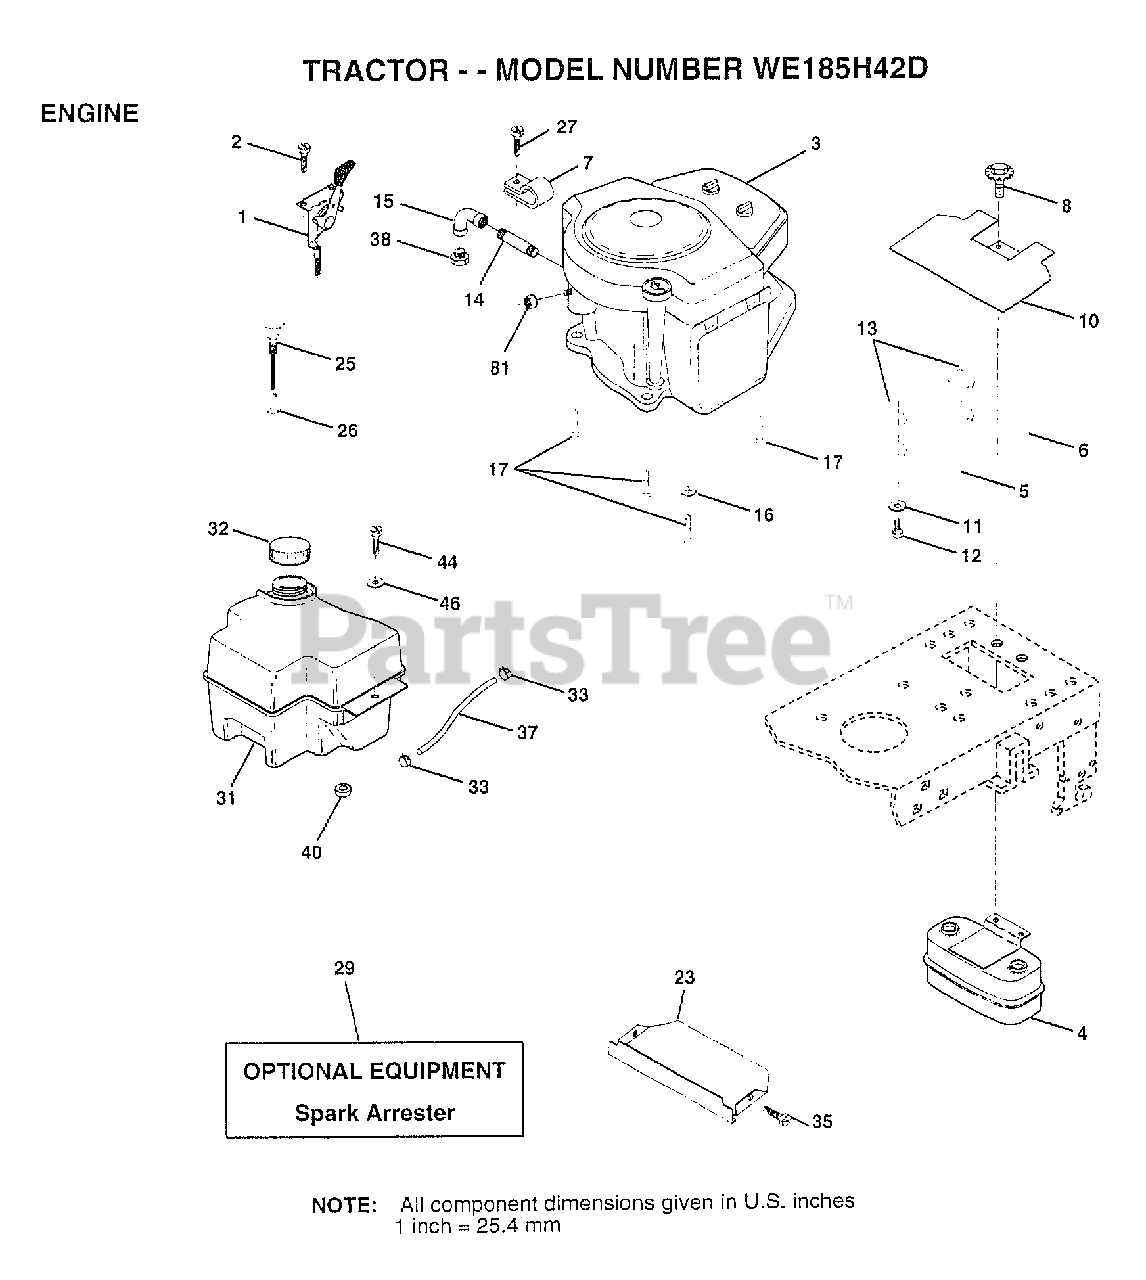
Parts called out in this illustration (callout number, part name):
1	CONTROL THRT 35.5
2	SCREW LT
4	MUFFLER.TW.LOTONE
5	EXHAUST.B&S.18.LH
6	EXHAUST.B&S.18.RH
7	CLAMP.TUBE.DBL.EN
8	BOLT.5/16-18.UNC
10	SHIELD.HEAT.
11	LOCKWASHER
13	GASKET MUFFLER
14	PIPE NIPPLE LT
15	ELBOW
16	LOCKWASHER
17	SCREW LT
23	SHIELD.BRN/DBR.GD
25	CONTROL.CHOKE.37
26	"NUT,KEPS 3/8-24IM"
27	"SCREW-TT,10-32 FL"
31	TANK.FUEL.FRONT.
32	CAP ASM FUEL
33	HOSE CLAMP
35	SCREW
37	LINE FUEL
44	SCREW HEX CRT
46	WASHER
81	NUT
